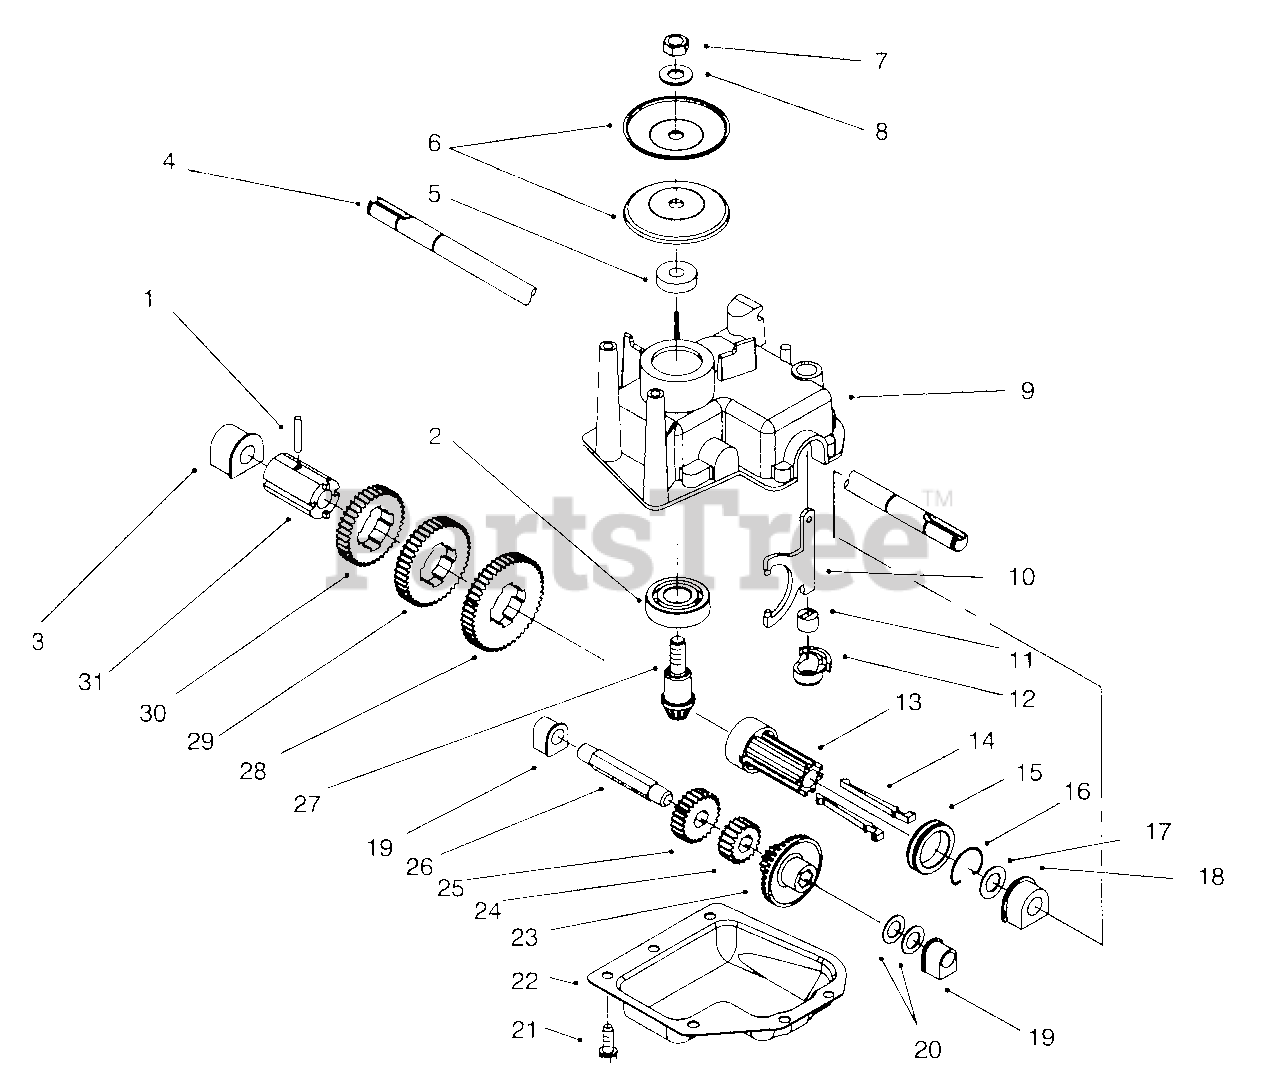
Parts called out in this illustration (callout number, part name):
1	Pin-Groove
2	Bearing-Ball
3	Bushing-Output
4	Shaft-Output
6	Pulley-Half
9	Gearcase-Upper
10	Yoke-Shift
11	Bushing-Yoke
12	Retainer-Shift Fork
13	Sleeve-Shift Key
14	Key-Shift
15	Collar-Shift
16	Clip-Spring
18	Bushing-Output
19	Bushing-Inter. Shaft
20	Washer-Thrust
22	Gear Case Cover
23	Pinion-15 Tooth
24	Pinion-20 Tooth
25	Pinion-25 Tooth
26	Shaft-Intermediate
27	Pinion-Bevel
28	Gear-49 Tooth
29	Gear-44 Tooth
30	Gear-39 Tooth
31	Sleeve-Gear
